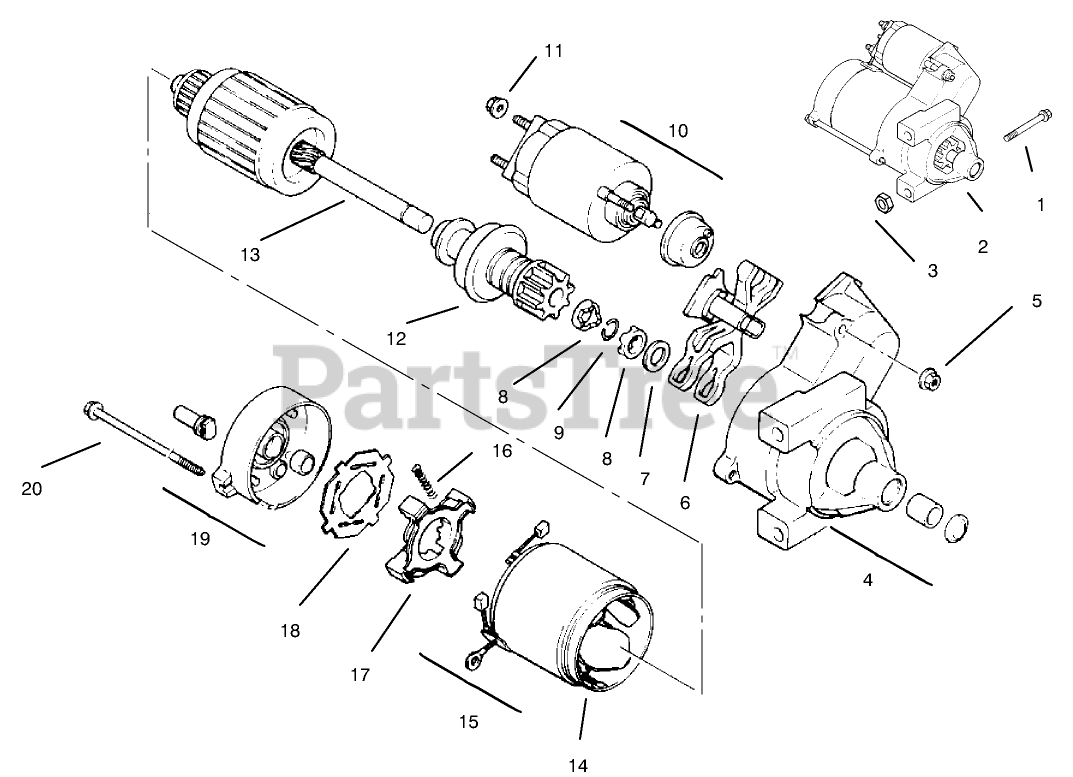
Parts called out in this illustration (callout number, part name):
2	Starter-Solenoid Shift (Incl. Ref. # 4-20)
4	Cap-End, Drive
5	Nut-Starter
6	LEVER-DRIVE, STARTER
7	Washer-Thrust
8	Nut-Stop Collar
9	Ring-Retainer
12	Drive-Pinion
13	Armature-Starter
14	Frame w/Brushes ASM
15	Kit-Brush (Incl. Ref. # 16)
16	Spring-Brush
17	Holder-Brush
18	Insulator
19	CAP-END, COMMUTATOR
20	Bolt-Thru
